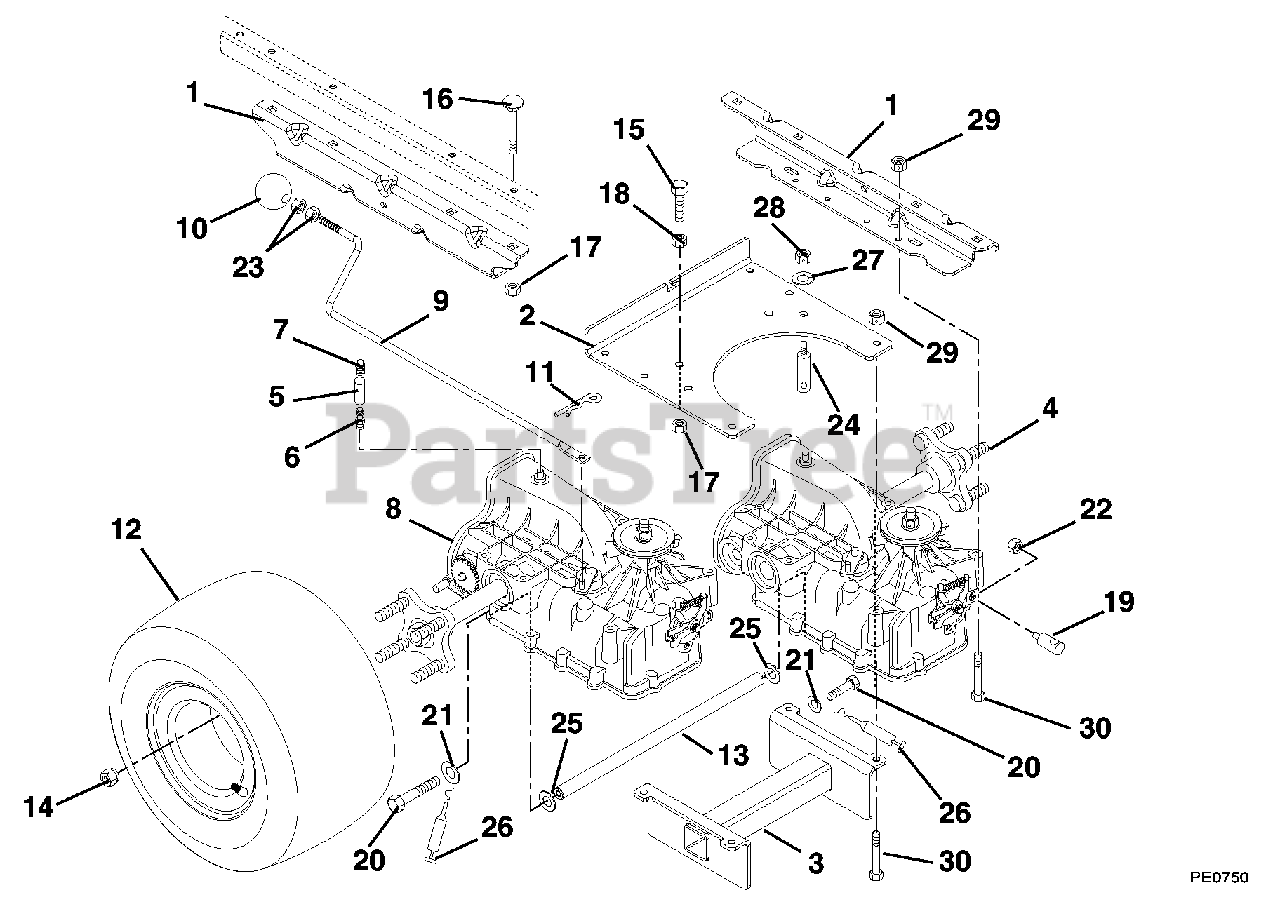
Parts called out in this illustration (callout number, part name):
1	Bracket, Transmission Axle
2	Bracket, Transmission Axle Support
3	Weldment, Transmission Axle Brace
4	Transaxle, Left Hand
5	Hose, Vent
6	Fitting, Straight .50 O-Ring Hydro-Gear
7	Cap, Vent .50 Hydro-Gear
8	Transaxle, Right Hand
9	Rod, Dump IZT
11	Pin, Hair
12	Assembly, Tire 9.5 x 18-2 Ply (036, 038, 040)
12	Assembly, Tire 8.5 x 18 2 Ply (034)
13	Rod, Axle Brace
14	Nut, Lug .50-20
15	Bolt, Hex .38-16 x 3.00 Grade 5
16	Bolt, Round Head Square Neck .38-16 x 2.25 Grade 5
17	Nut, Locking Top Flange .38-16
18	Nut, Flange .375-16
19	Rod Pivot
20	Bolt, Hex .31-18 x 2.50 Grade 5
21	Washer, Locking .31 x .078 Regular
22	Nut, Locking Top Flange .31-18
23	Nut, Jam .312-18
24	Shoulder Stud
25	Washer, Flat Steel .38 x .87 x .179
26	Adhesive Sealant
27	Washer, Locking .38 x .094 Regular
28	Nut, Hex .38-16
29	Nut, Locking Nylon .312-18
30	Bolt, Hex .31-18 x 2.75 Grade 5
